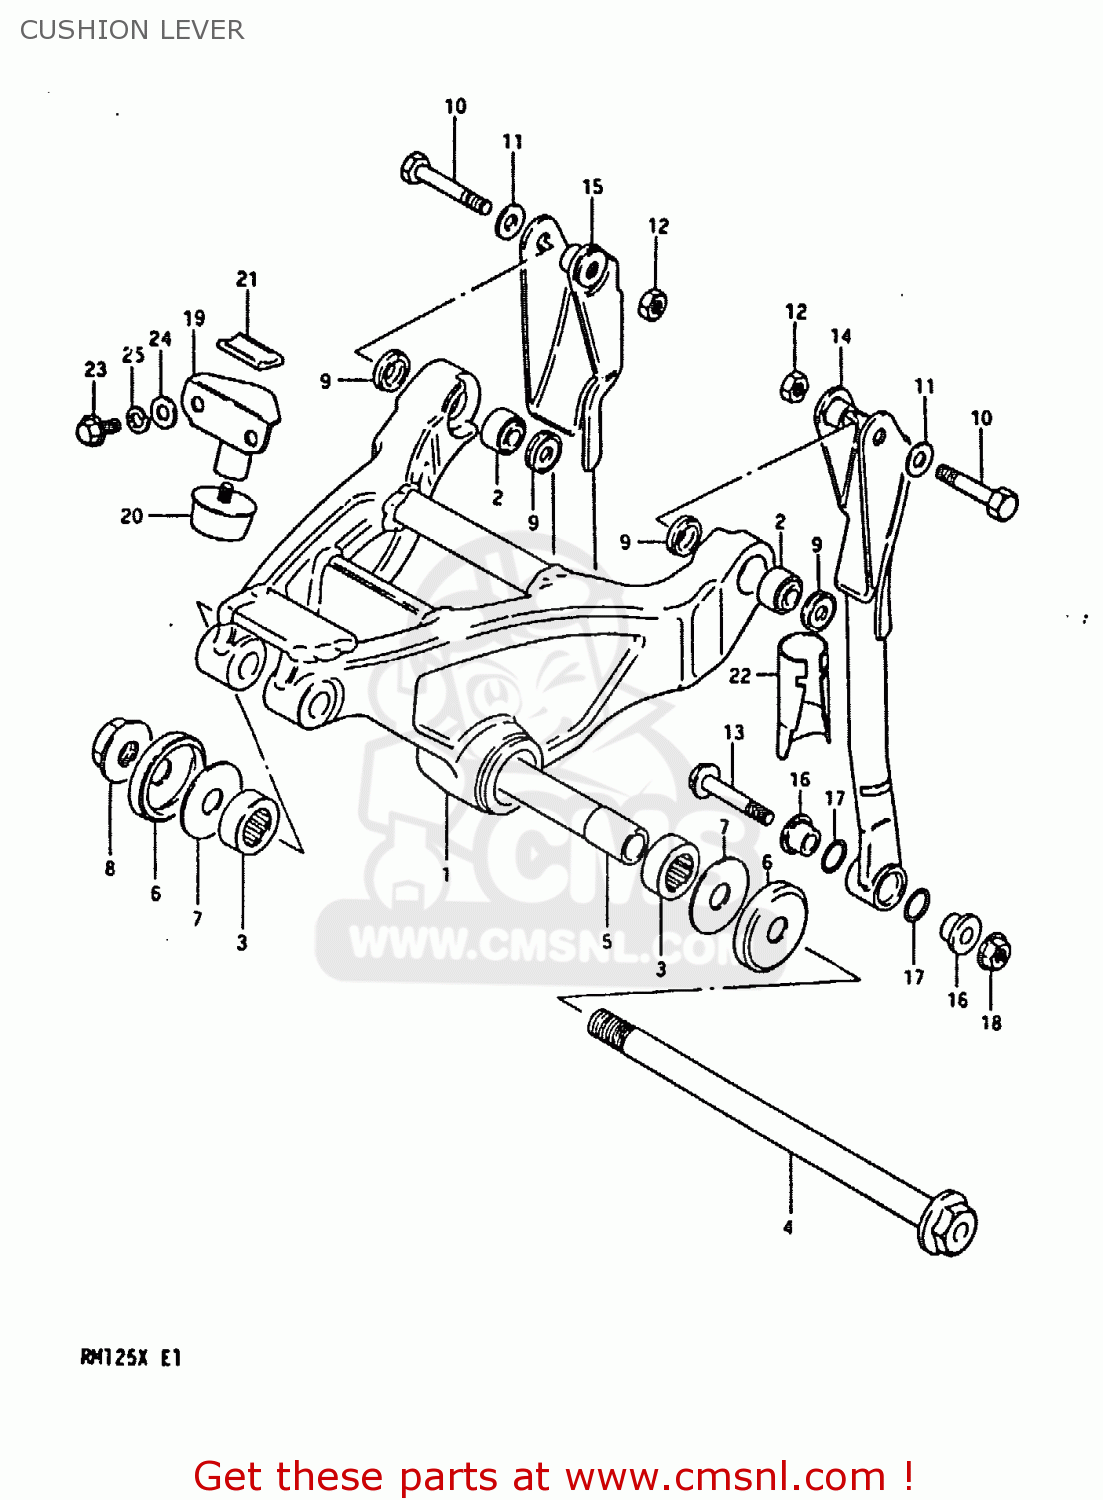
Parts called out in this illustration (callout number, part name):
1	LEVER SET,REAR CUSHION
2	SPHERICAL BRNG,TORQUE LINK
3	BEARING(17X26X20)
4	SHAFT,REAR CUSHION LEVER
5	SPACER,REAR CUSHION LEVER
6	SEAL,REAR CUSHION LEVER
7	WASHER(12X35X2)
8	NUT 12MM
9	10
10	BOLT 8X38
11	WASHER
12	NUT
13	BOLT(8X45)
14	ROD,REAR CUSHION LEVER
15	BOLT,REAR CUSHION LEVER
16	SPACER,RR CUSHION ROD LWR
17	O RING(D:1.9,ID:13)
18	NUT
19	STOPPER,TENSION
20	RUBBER,TENSION STOPPER
21	SUPPORTER, RUBBER
22	PROTECTOR,REAR CUSHION R
23	BOLT
24	WASHER
25	LOCK WASHER
